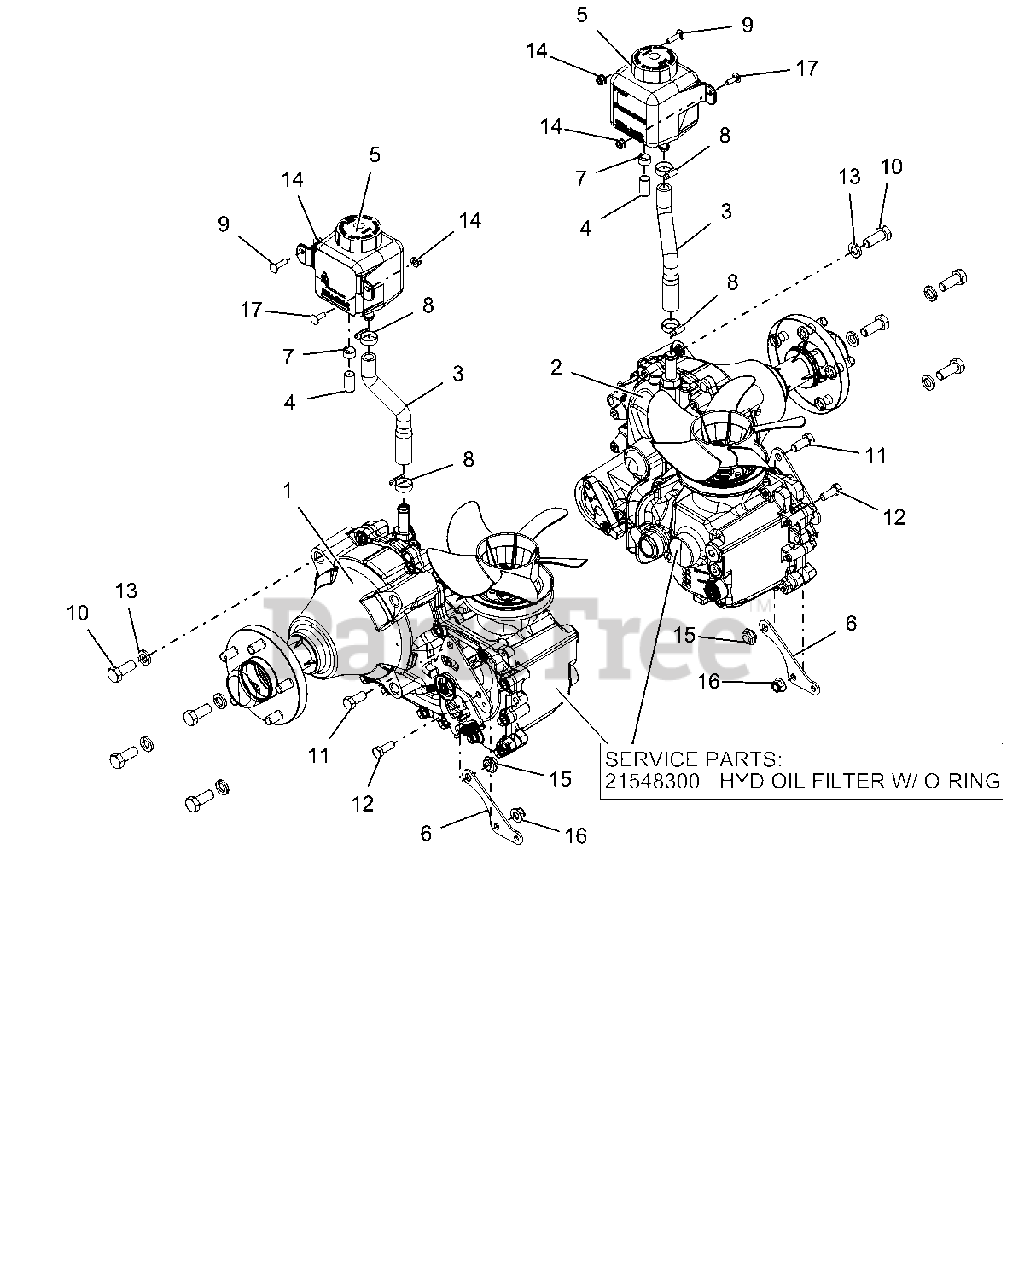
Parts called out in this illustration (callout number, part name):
1	TRANS, RH HG ZT-5400
2	TRANS, LH HG ZT-5400
3	HOSE,PT200/400 TRANS OVERFLOW
4	CAP, .50 BARBED FITTING
5	TANK, HYDRO OVERFLOW 700 ML
6	BRKT,DRIVE CONTROL LINKAGE MTG
7	CLAMP, .62 SPRING
8	CLAMP,.88 DIA. HOSE
9	@BLT-RDHDSQNK .25-20X1.00 G5YZ
10	@BLT-HEX .50-13X1.25 GR5 YWZC
11	@BLT-HEX .44-14X1.00 GR5 YWZC
12	@BLT-HEX .38-16X1.00 GR5 YWZC
13	@WSHR-LK .50X.125 REG YWZC
14	@NUT-LK-NYL-FLG .25-20 YWZC
15	@NUT-LK-NYL-FLG .44-14 YWZC
16	@NUT-LK-NYL-FLG .38-16 YWZC
17	BLT-RDHDSQNK .25-20X.75 G5YZ
18	FILTER,HYD OIL W/ORING ZT-54OO
